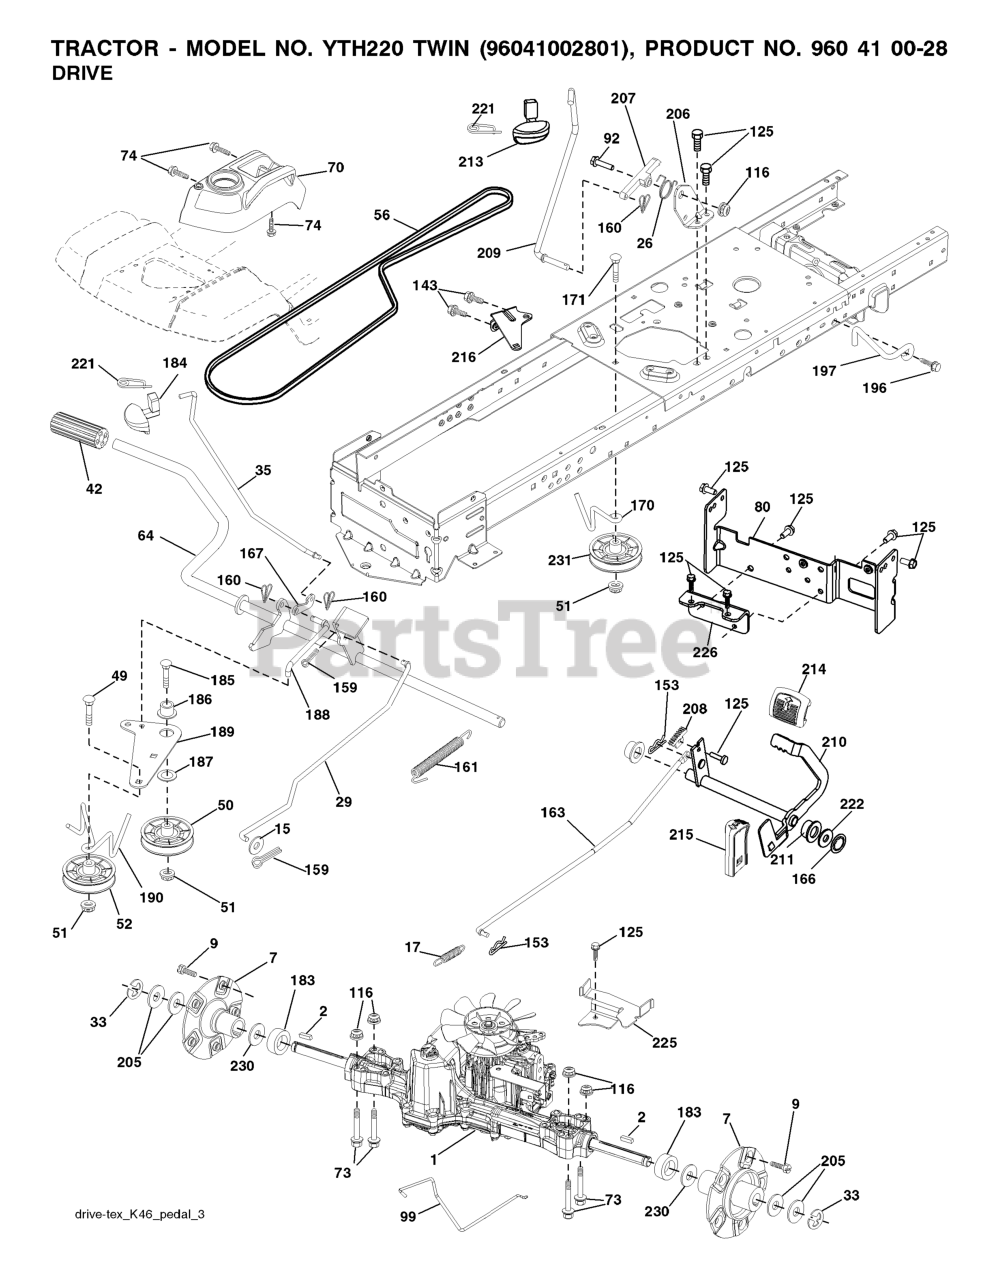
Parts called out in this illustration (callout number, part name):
2	KEY.SQUARE.187X2.500
7	HUB.ASM.WHEEL.REAR.22"
15	WASHER
17	SPRING.BRAKE.K46.GREEN
26	SPRING.RETURN.CRUISE
29	ROD.BRAKE.K46
35	ROD.BRAKE.PARKING.GT.H
42	PEDAL COVER T
50	IDLER.FLAT.910.OFFSET
51	NUT LOCK FLG 3/8-16 UNC
52	IDLER.V-GROOVE.910.OFFSET
56	V-BELT.MOWER.92.40.42/K46
64	SHAFT.ASM.PEDAL.BRK.CNTR
70	RP CONSOLE.ASM.PCH.W/TB
73	BOLT HEX 5/16-18 GR 5
74	SCREW.HI-LO.CONSOLE
80	STRAP TORQUE
92	BOLT
99	ROD.SPRING.BYPASS.K46.LT.Z
116	NUT LOCK HEX FLANGE 5/16-18
125	SCREW
143	Screw 5/16-18 x 1/2 Hex, Self Tapping 5/16-18 x 1/2
153	RETAINER M
159	COTTER PIN
160	RETAINER CLIP
161	SPRING, RETURN LT
163	ROD.CONTROL.PEDAL.K46
166	NUT.PUSH.625.2006
167	LATCH.BRAKE.SPRING
170	KEEPER.V-IDLER.CENTER.
183	SPACER.SPLIT.800X.350
184	HANDLE.PARKG.BRK.HUSQ X667
186	SPACER.RETAINER
187	WASHER 12/32X2X10GA
188	RP.LINK.CLUTCH.GROUND.DRIVE
189	BELLCRANK.GROUND.DRIVE.TEX.
190	KEEPER.BELLCRANK.DRIVE
196	SCREW 3/8-16X1
197	LINK.CLUTCH.ANIT-ROTAT
206	BRKT.MOUNT.LATCH.CRUIS
207	LATCH.CONTROL.CRUISE
208	GEAR.SECTOR.CONTROL.CR
209	ROD.CONTROL.CRUISE.GT.
210	ROCKER.ASM.PEDAL.CONTR
211	BEARING.NYLON
213	KNOB.CONTROL.CRUSIE.HU
214	PEDAL.FORWARD.TEX.GT.4
215	PEDAL.REVERSE.TEX.GT.4
216	BRACKET.PULLEY.IDLER.W/TEX
220	REFLECTOR.RH.TEX GT
221	RETAINER.SPRING.CLIP.H
222	WASHER 21/32 X 1-1/4 X 10 GA.
225	KEEPER.BELT.TRANSAXLE.K46
226	BRACKET.MOUNT.TORQUE.K46.TLT
230	WASHER.HARDENED
